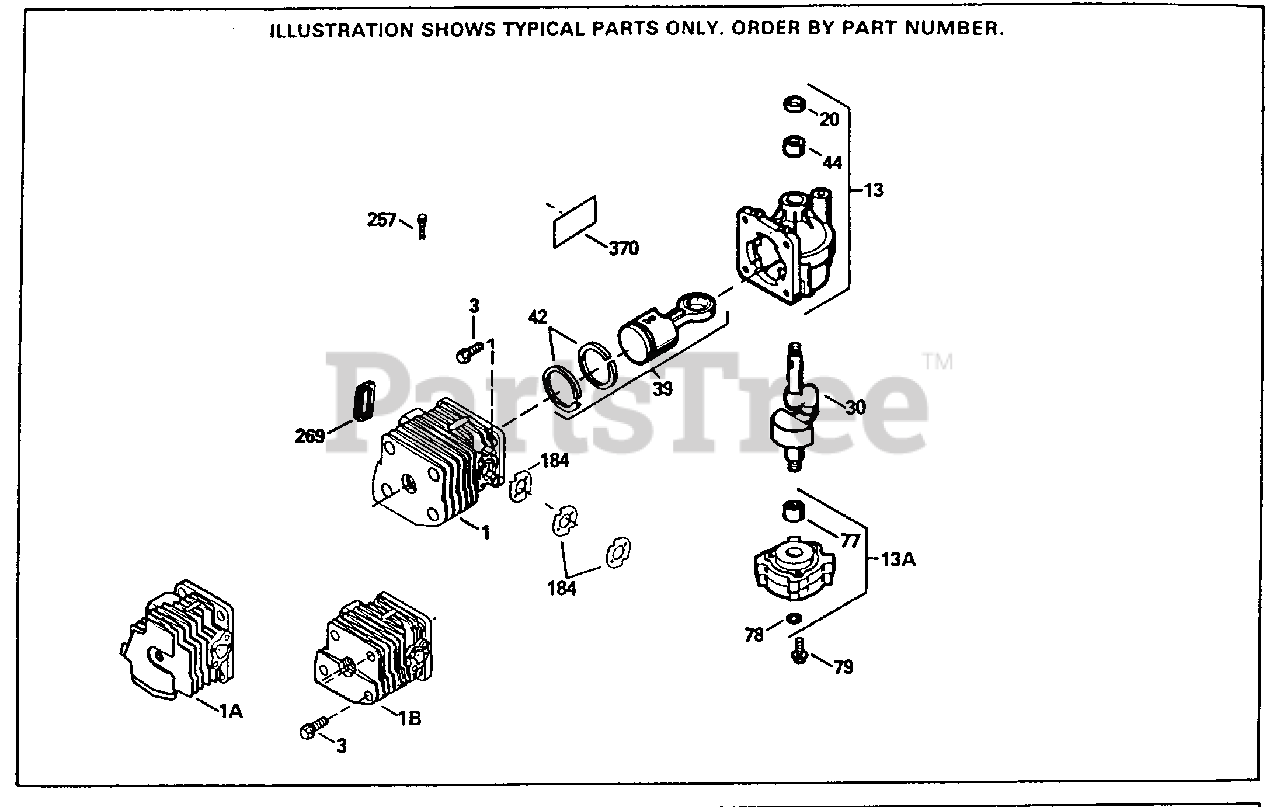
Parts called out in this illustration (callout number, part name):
1A	"Cylinder
3	Screw, Torx 1/4-20 x 43/64"
13	Crankcase Assy. (Incl. 20 & 44)
13A	Cover Assy., Crankcase Incl. 77 & 78
20	Seal, Oil
30	Crankshaft
39	Piston & Rod Assy. (Incl. 42)
42	Ring Set, Piston
44	Bearing, Cartridge
77	Bearing, Cartridge
78	Seal, Oil
79	Screw, 1/4-20 x 3/4"
184	Gasket, Adapter
257	Screw, 10-24 x 1/2"
269	Gasket, Exhaust
370	Decal, Instruction
